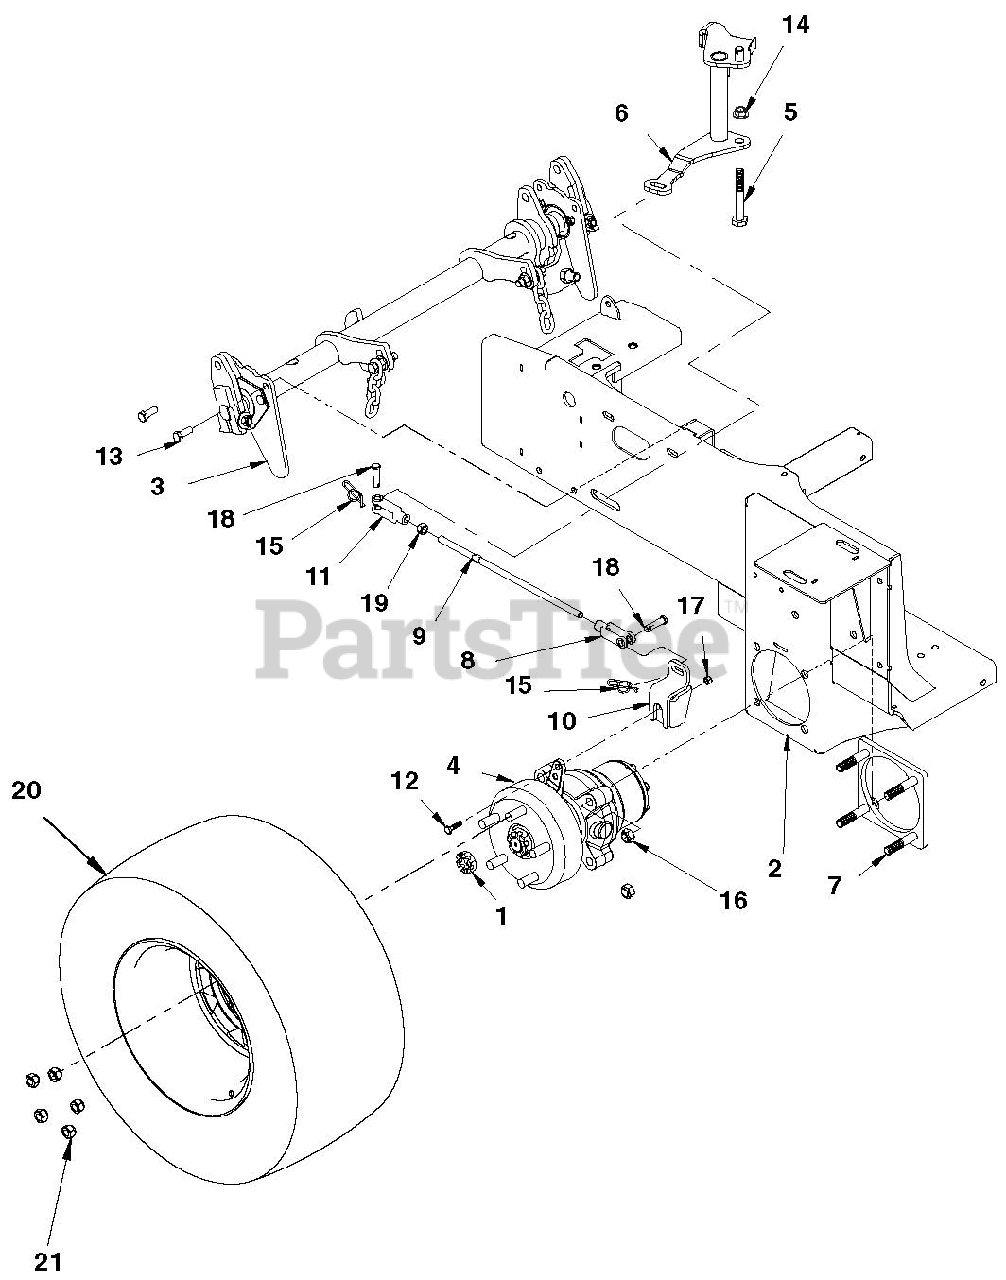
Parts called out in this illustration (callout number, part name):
1	NUT, 1-20 SPECIAL CASTLE S/O
2	FRAME WITH DECALS ACM
3	Rear Lift Rod Assembly
4	MOTOR, LH HYDRO GEAR WHEEL
4	MOTOR, RH HYDRO GEAR WHEEL
5	BRG, FLG .502X.629X.421
6	WLDT, LH PARK BRAKE CONTROL
6	WLDT, RH PARK BRAKE CONTROL
7	WLDT, WHEEL MOTOR PLATE
8	YOKE, 3/8-24 LH ADJUSTABLE
9	ROD, STRAIGHT PARK BRAKE CONTR
10	WLDT, BRAKE ARM EXTENSION
11	YOKE, 3/8-24 RH ADJUSTABLE
12	BOLT, 1/4-20X1.00 HEX 5 Y
13	BOLT, 3/8-16X1.00 HEX 5 Y
14	BOLT, 1/2-13X2.75 HEX 5 Y
15	RING, RUE .375 X .054 X 1.254
16	NUT, 1/2-13 STD HEX GR5 Y
17	LOCKNUT, 1/4-20 NYLOC Y
18	PIN, CVS .375X1.38X1.14 Y
19	NUT, 3/8-24 STD HEX Y
20	TIRE/WHEEL ASSY, 24X11.50-12
20	TIRE, 24X11.50-12
20	RIM, 12X8.5
21	NUT, 1/2-20 LUG C
